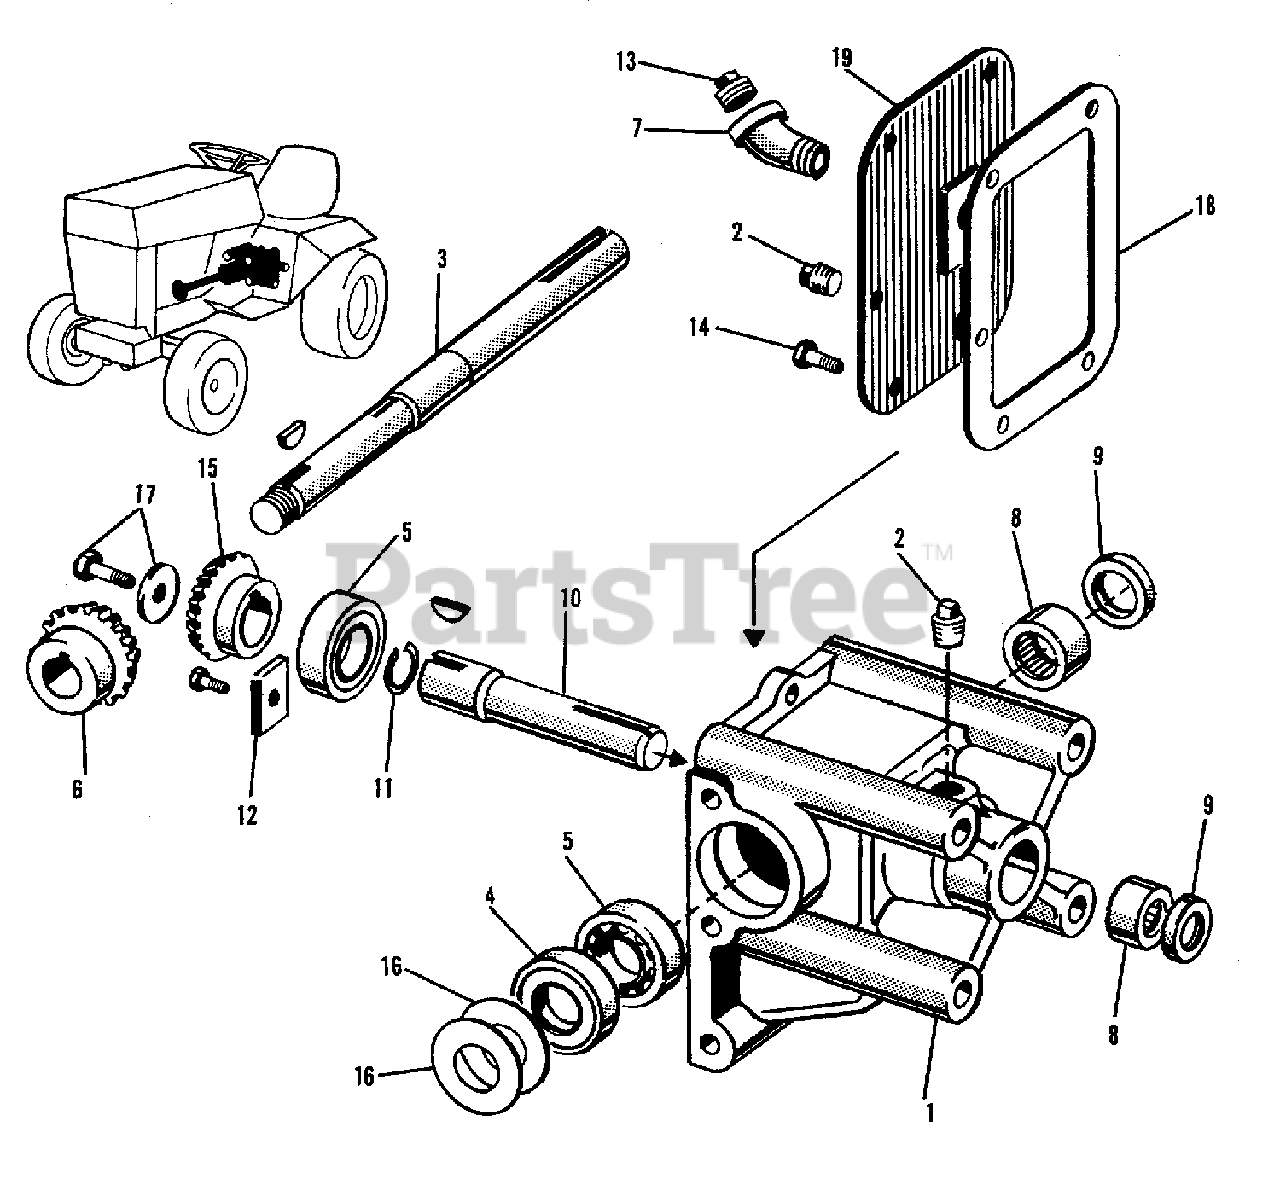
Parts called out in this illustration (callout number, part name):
1	HOUSING, Bevel Gear Box
2	PLUG, Pipe, 1/4 Standard (Square Head)
3	SHAFT, Driven (Variable Speed)
3	SHAFT, Driven (Hydrostatic)
3	KEY, Woodruff, 3/16 x 3/4 (Variable Speed)
3	KEY, Hi-Pro, #606 (Hydrostatic)
4	SEAL, Oil
5	BEARING, Ball
6	GEAR, Bevel (Driven)
7	ELBOW, Street, 3/8 x 90 Degrees
8	BEARING, Needle
9	SEAL, Oil
10	SHAFT, Driver
10	KEY, Woodruff, 3/16 x 3/4
11	RING, Retaining
12	PLATE, Bearing Clamping
12	CAPSCREW, 5/16NC x 5/8
12	LOCKWASHER, 5/16
13	PLUG, Pipe, 3/8 Standard (Square Head)
14	CAPSCREW, 1/4NC x 5/8 (w/Inter Tooth Lockwasher)
15	GEAR, Bevel (Driven)
16	SHIM, Inner (Use as Required)
16	SHIM, Outer
17	CAPSCREW, 5/16NC x 3/4, GR8
19	COVER, Housing
19	WASHER, 7/16, Standard
